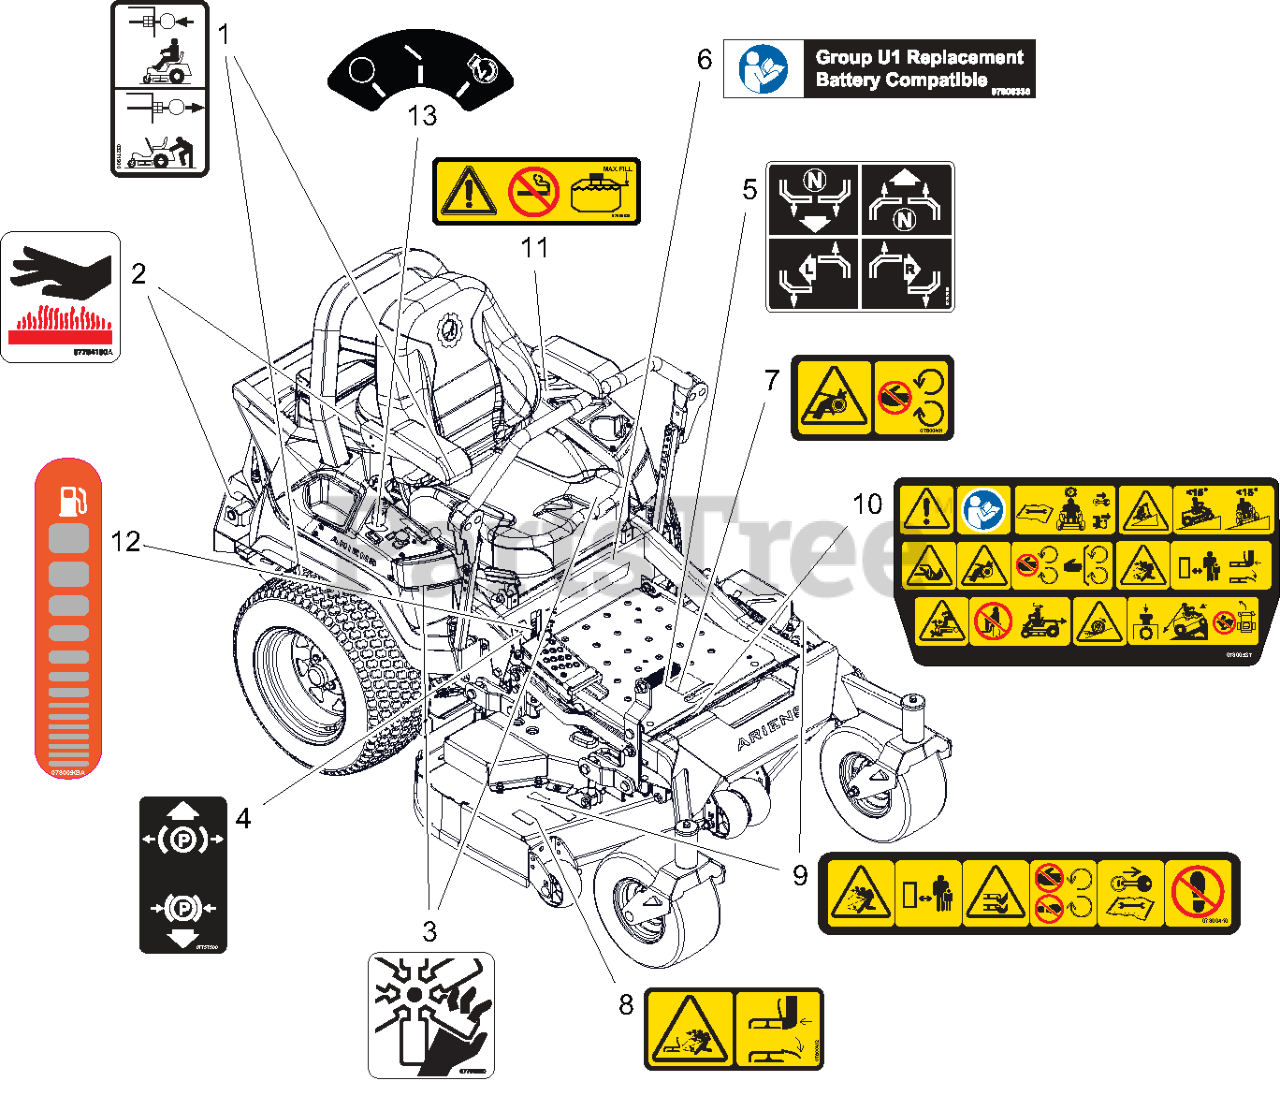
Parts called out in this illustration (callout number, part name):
1	DECAL, TRANSMISSION DISCONNECT
2	DECAL, HOT SURFACE
3	DECAL, DANGER FAN
4	DECAL, PARKING BRAKE LEVER
5	DECAL, INSTRUCTIONAL-STEERING
6	DECAL, U1 BATTERY REPLACEMENT
7	DECAL, SAFETY - GUARDING
8	DECAL, SAFETY - DECK GUARDING
9	DECAL, DECK SAFETY
10	DECAL, MAIN SAFETY
11	DECAL, FUEL WARNING
12	DECAL, ARIENS FUEL LEVEL
13	DECAL, KEYSWITCH
